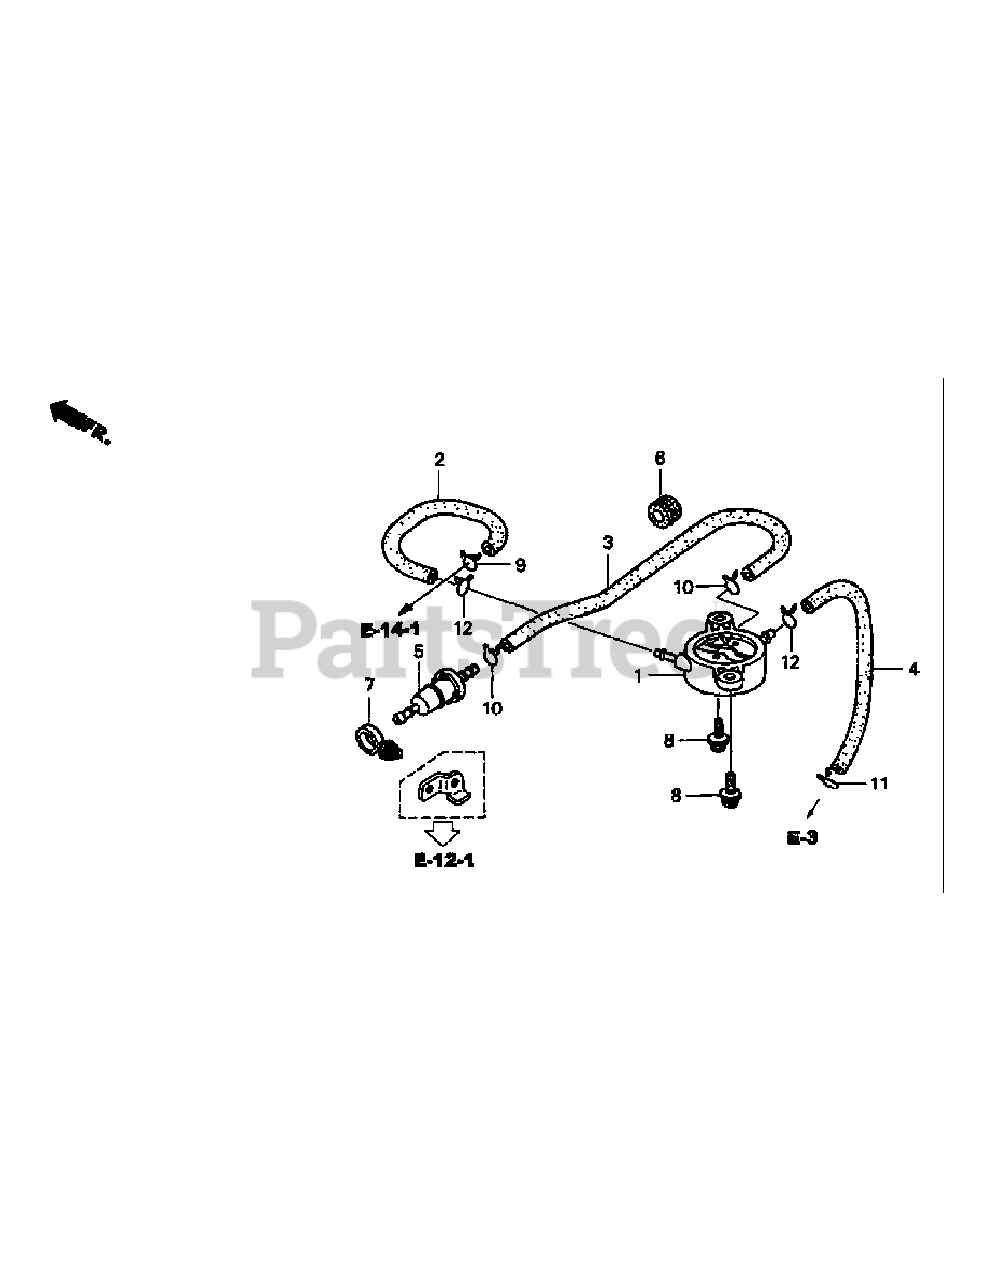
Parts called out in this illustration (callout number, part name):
1	Fuel Pump Assy.
2	Fuel Line To Carburetor
3	Fuel Line To Filter
4	Diaphragm Line
5	Fuel Filter
6	Reserve Tank Grommet
7	Wire Harness Clip
8	Screw Washer (6x16)
9	Tube Clip
10	Tube Clip
11	Tube Clip
12	Tube Clip
